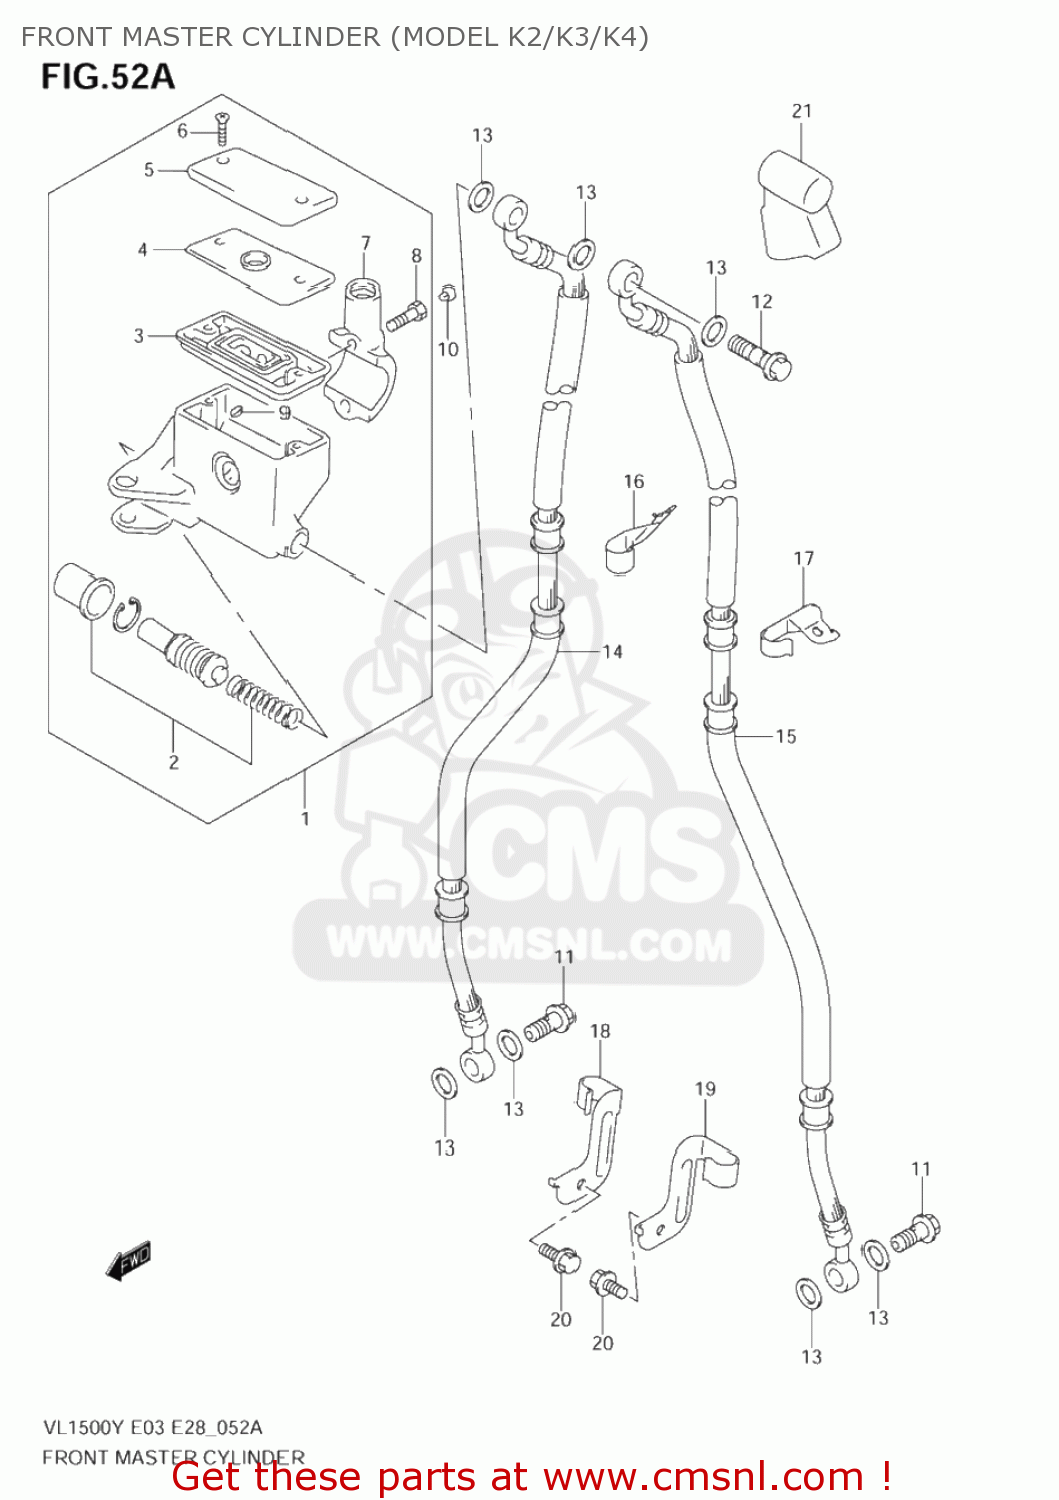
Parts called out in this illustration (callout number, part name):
1	CYLINDER ASSY,FR MASTER
2	PISTON & CUP SET
3	4
4	PLATE,DIAPHRAGM
5	CAP
6	SCREW
7	HOLDER
8	BOLT
9	PROTECTOR
10	CAP(OD:10)
11	BOLT UNION
12	BOLT UNION
13	WASHER(10X15X1.5)
14	HOSE,FR BRAKE,R
15	HOSE,FR BRAKE,L
16	CLAMP,FR BRAKE HOSE UPR
17	CLAMP,FR BRAKE HOSE UPR,L
18	CLAMP,FR BRAKE HOSE,R
19	CLAMP,FR BRAKE HOSE,L
20	BOLT(6X12)
21	BOOT,FR MASTER CYLINDER
